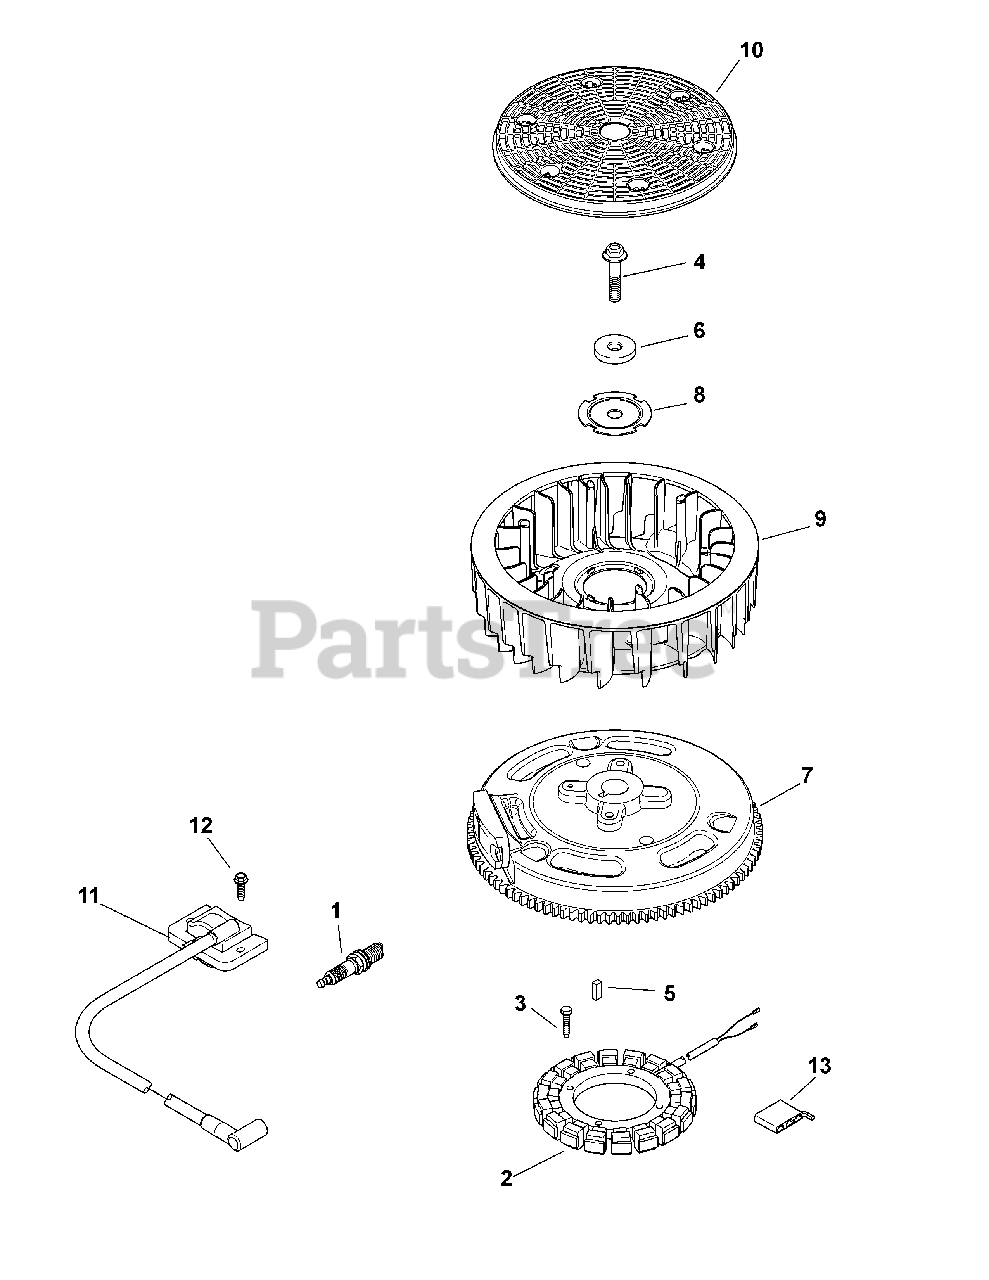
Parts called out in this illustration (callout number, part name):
1	Spark Plug
2	15 Amp Stator Kit
3	Screw, M5 x 0.8 x 25
4	Hex Flange Screw
7	Flywheel Assembly
8	Fan Mounting Plate
9	Fan
11	Module Ignition Kit
12	Screw, M5 x .8 x 20
